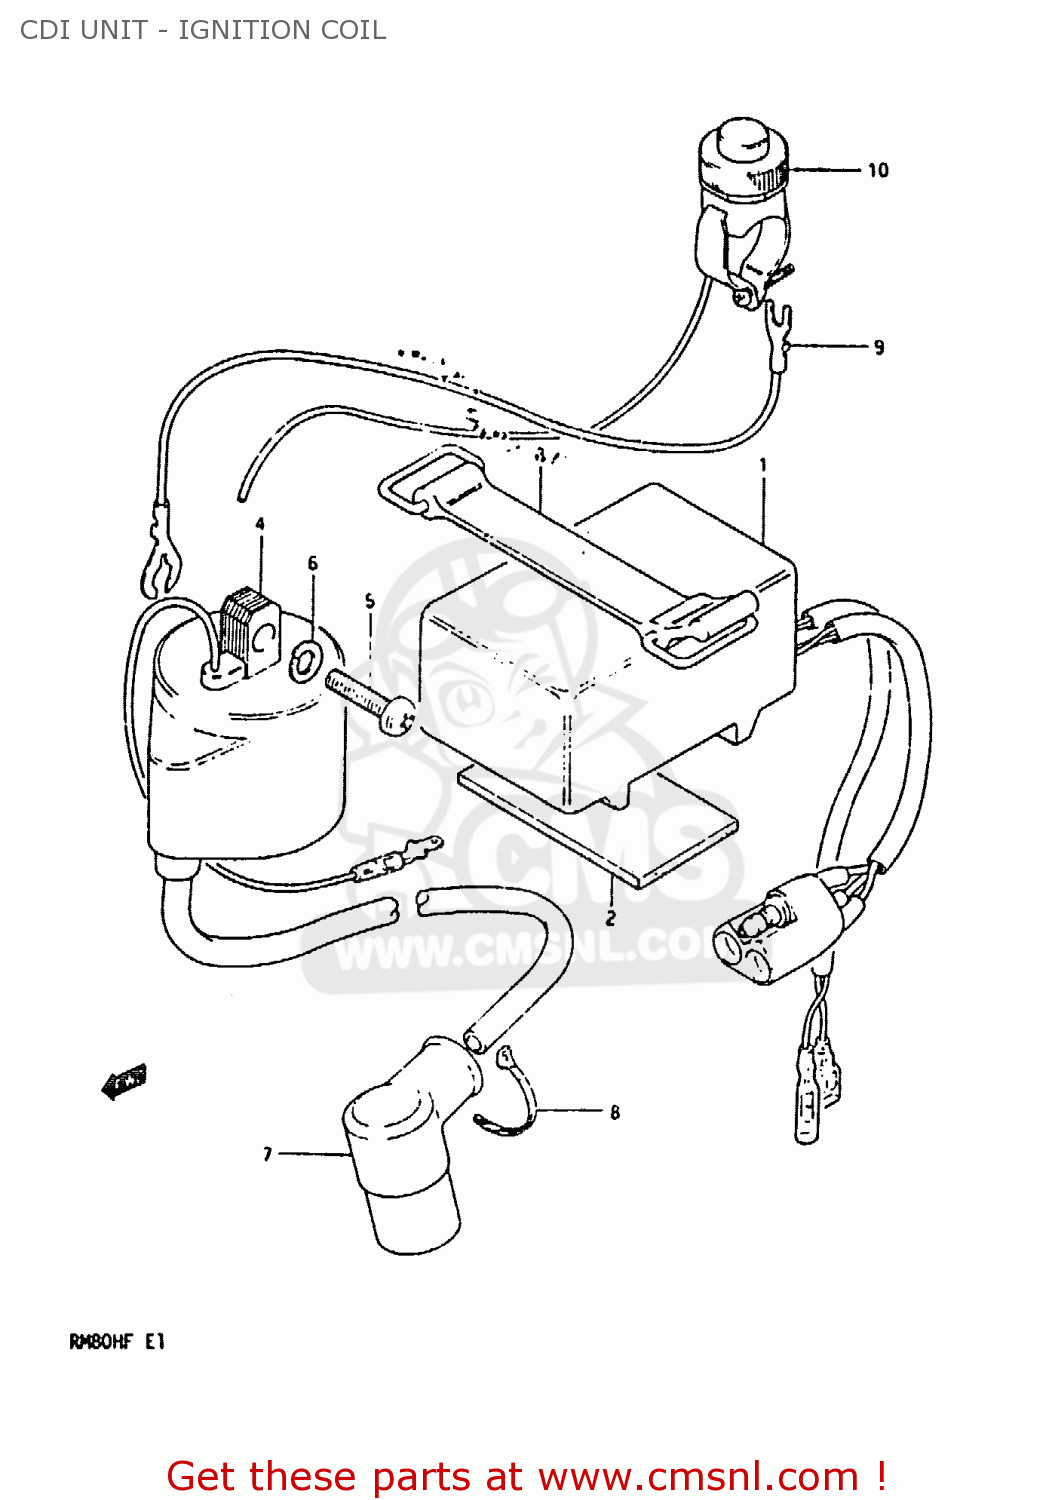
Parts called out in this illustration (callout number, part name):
1	CDI UNIT
2	PROTECTOR(170X95X3.0)
3	BAND
4	COIL ASSEMBLY,IGNITION
5	SCREW
6	LOCK WASHER
7	CAP,SPARK PLUG
8	CLAMP
9	WIRE,ENGINE STOP EARTH
10	SWITCH ASSEMBLY
